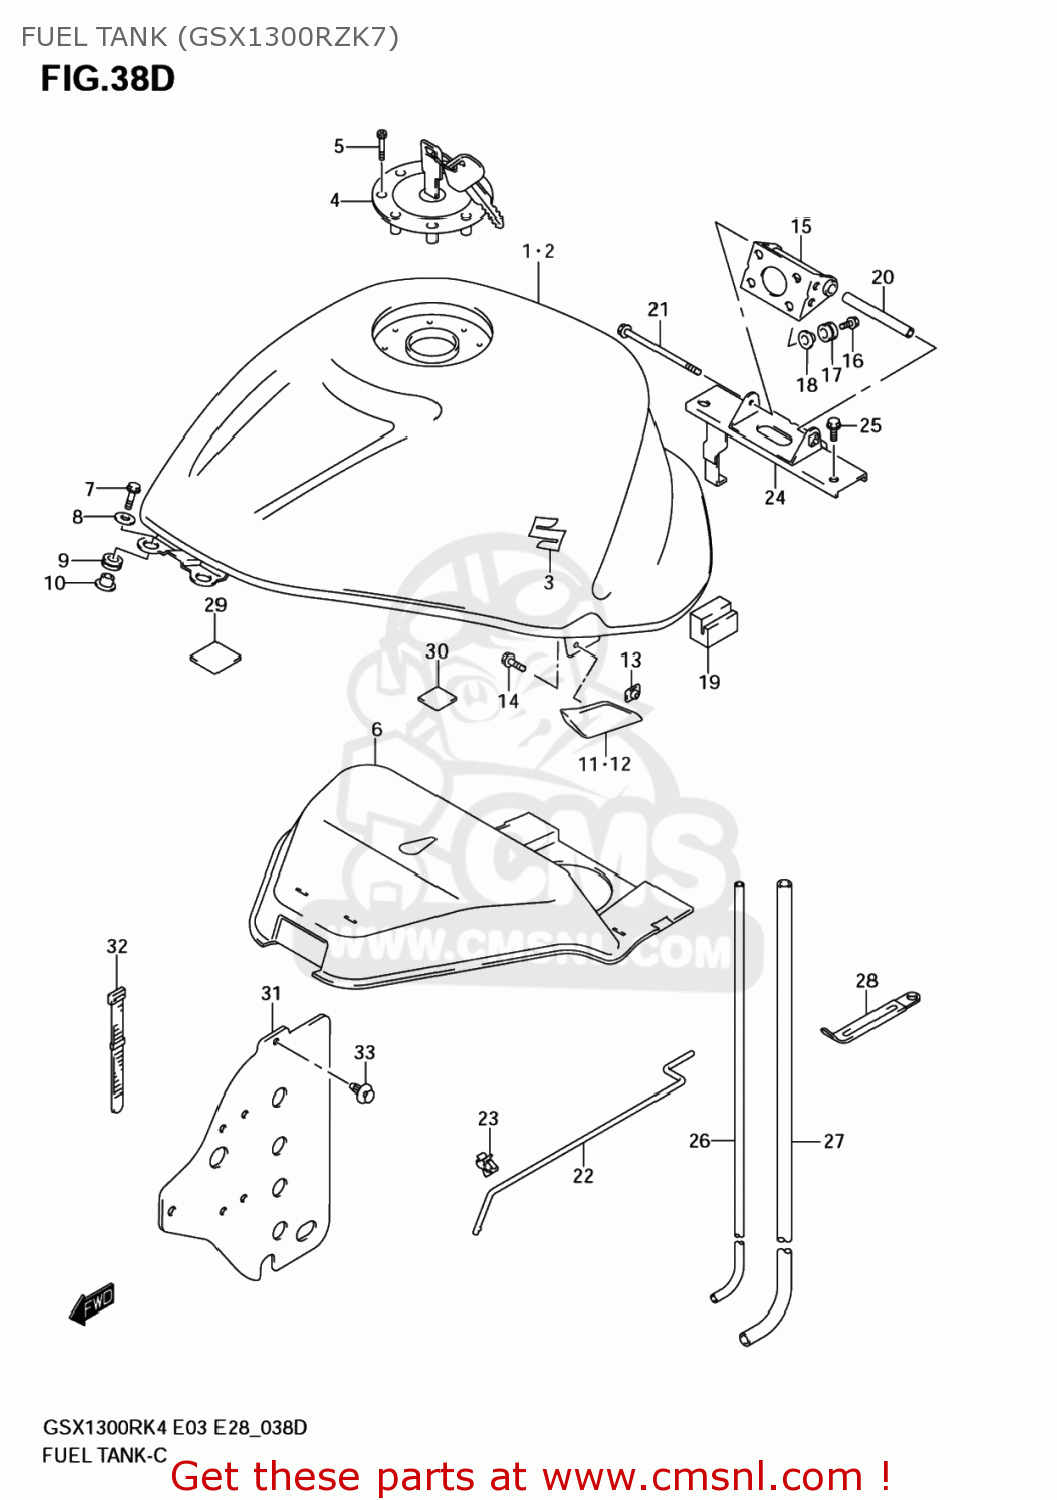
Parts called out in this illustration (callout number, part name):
1	TANK ASSY,FUEL(RED)
2	TANK ASSY,FUEL(RED)
3	EMBLEM,S
4	CAP SET,FUEL TANK
5	BOLT(5X20)
6	SHIELD,FUEL TANK HEAT
7	SCREW(6X25)
8	WASHER(6.5X18X1.5)
9	CUSHION
10	WASHER
11	COVER,FUEL TANK SIDE,R
12	COVER,FUEL TANK SIDE,L
13	PLATE,FUEL TANK SIDE
14	SCREW
15	BRACKET,FUEL TANK RR NO.1
16	BOLT(6X20)
17	CUSHION
18	WASHER
19	CUSHION,FUEL TANK SIDE
20	SPACER,FUEL TANK RR
21	BOLT
22	STAY,FUEL TANK
23	CLAMP
24	BRACKET,FUEL TANK RR NO.2
25	BOLT
26	HOSE,FUELTANK BREATHER
27	HOSE(7X11X600)
28	CLAMP(L:65)
29	CUSHION
30	CUSHION,FUEL TANK COVER
31	SHEET,HEAT SHIELD RUBBER
32	CLAMP(L:165)
33	CLIP(BLACK)
